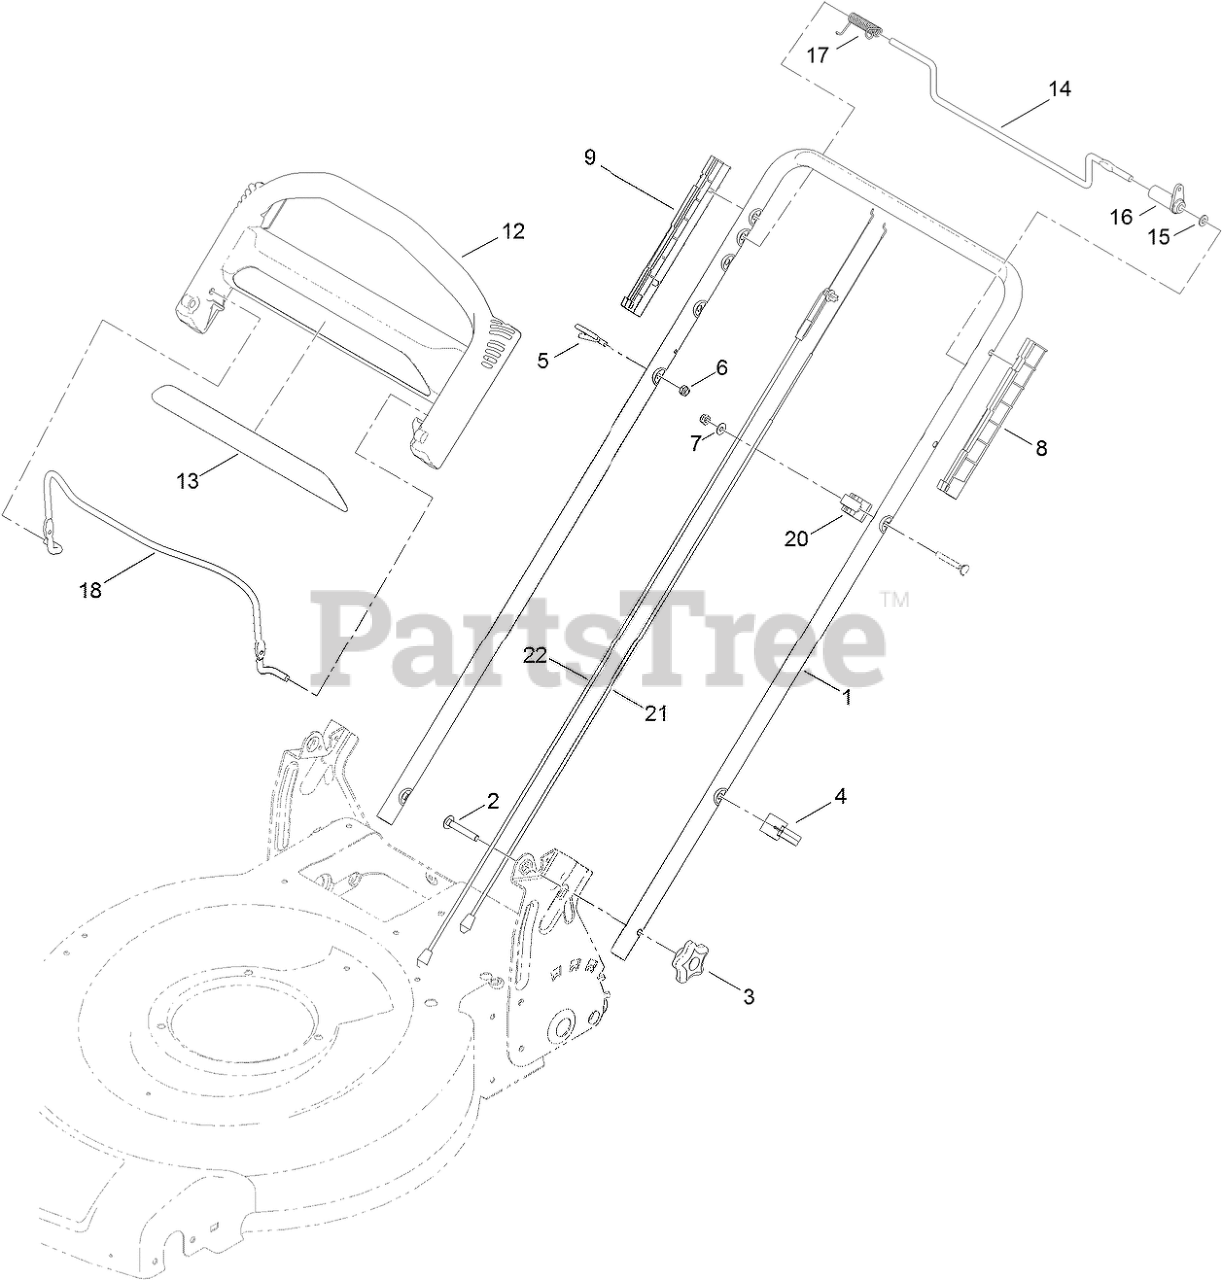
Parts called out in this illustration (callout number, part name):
2	Screw-CARR
3	KNOB-HANDLE
4	GUIDE-CABLE
5	GUIDE-ROPE
6	NUT-LOCK, NI
7	WASHER-FLAT
8	GUIDE-LH
9	GUIDE-RH
12	HANDLE-CONTROL
14	BAR-CONTROL, TRACTION
15	WASHER-PLAIN
16	LEVER-TRACTION
17	Spring-Torsion
18	Bail-Brake
20	ANCHOR-CABLE
21	CABLE-TRACTION
22	CABLE-BRAKE
